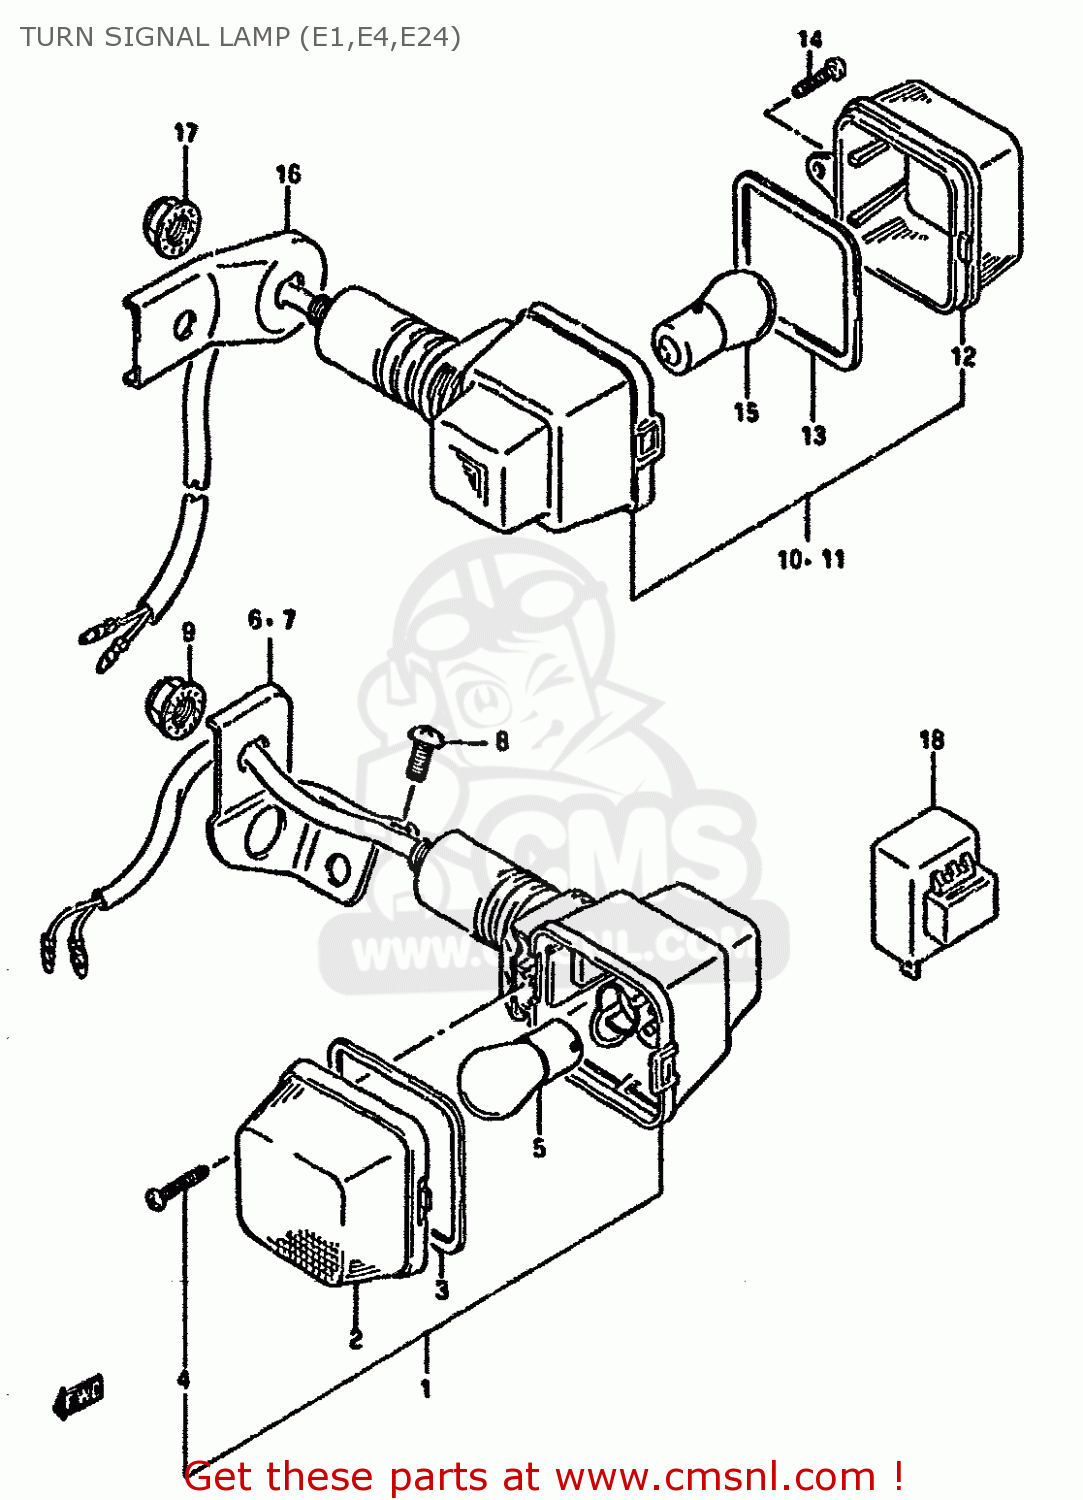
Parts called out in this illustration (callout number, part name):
1	LAMP,REAR TURN SIGNAL LH
2	LENS
3	GASKET (NAS)
4	SCREW
5	BULB 12V 21W
6	BRACKET,FRONT TURN SIGNAL,RIGHT
7	BRACKET,FRONT TURN SIGNAL
8	SCREW
9	NUT
10	LAMP,REAR TURN SIGNAL LH
11	LAMP,REAR TURN SIGNAL RH
12	LENS
13	GASKET (NAS)
14	SCREW
15	BULB 12V 21W
16	BRACKET,RR TURNSIGNAL LAMP
17	NUT
18	RELAY,TURN SIGNAL
